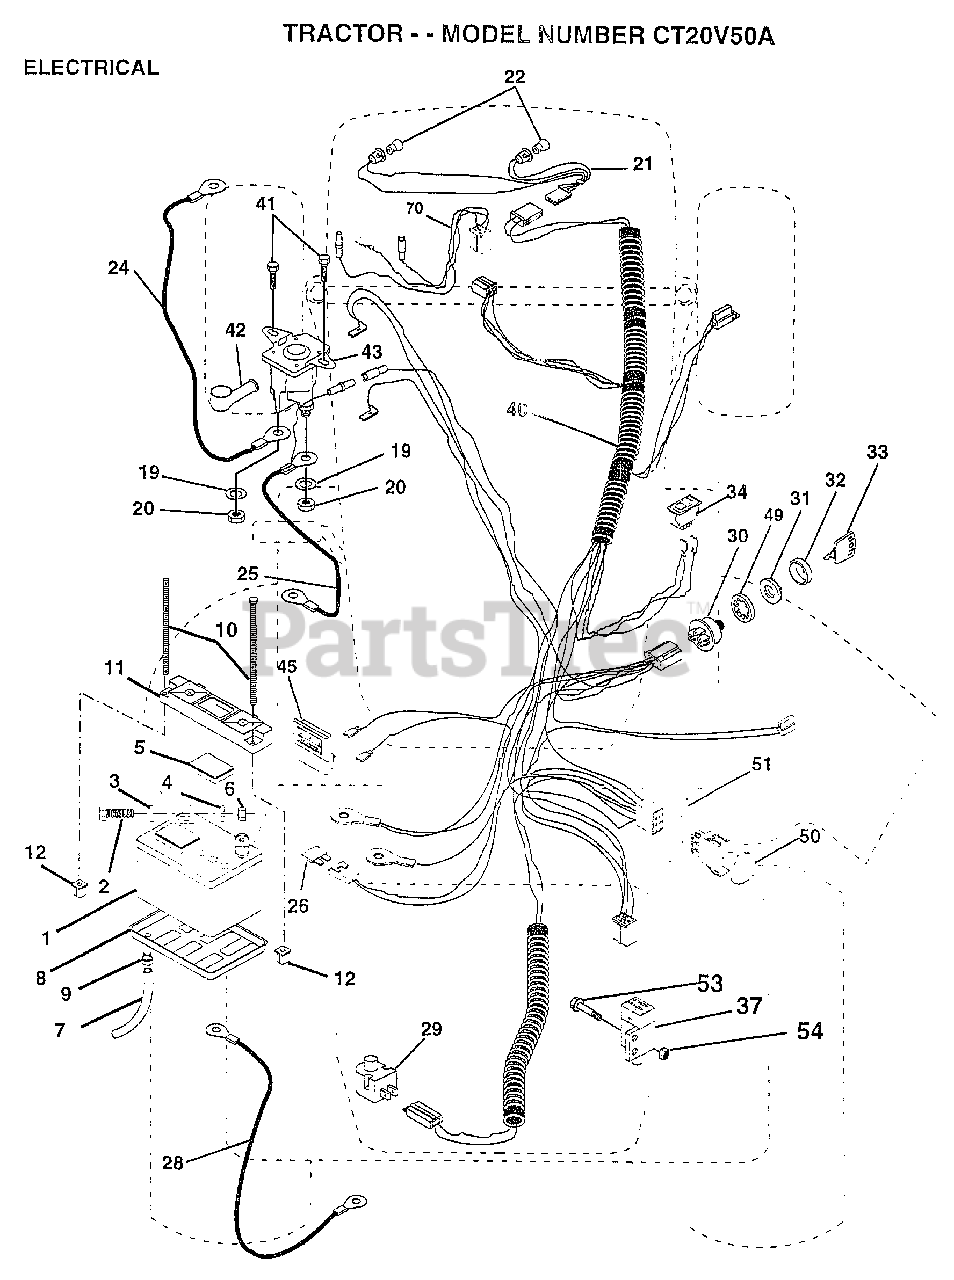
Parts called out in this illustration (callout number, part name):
3	WASHER
4	LOCKWASHER
5	"CAP,BATTERY "
7	"DRAIN TU T, BATT"
8	"TRAY T, BATTERY"
9	HOSE CLAMP T
20	NUT
21	"HARNESS,LIGHT SOC"
22	HEADLAMP BULB
24	CABLE-BATTERY T
25	CABLE.6GA.12.5.
26	FUSE HYT
28	CABLE T
29	SWITCH SEAT
32	COVER KEY SWITCH
33	KEY MLD GEN DELTA
34	SWITCH LT
37	SWITCH INTERLOCKT
40	HARNESS.IGN.SRSGT
41	SCREW
45	AMMETER
49	LOCKWASHER
51	RING RETAIN PTO
53	SCREW
54	"NUT,KEPS"
70	HARNESS.ENG.VANII
